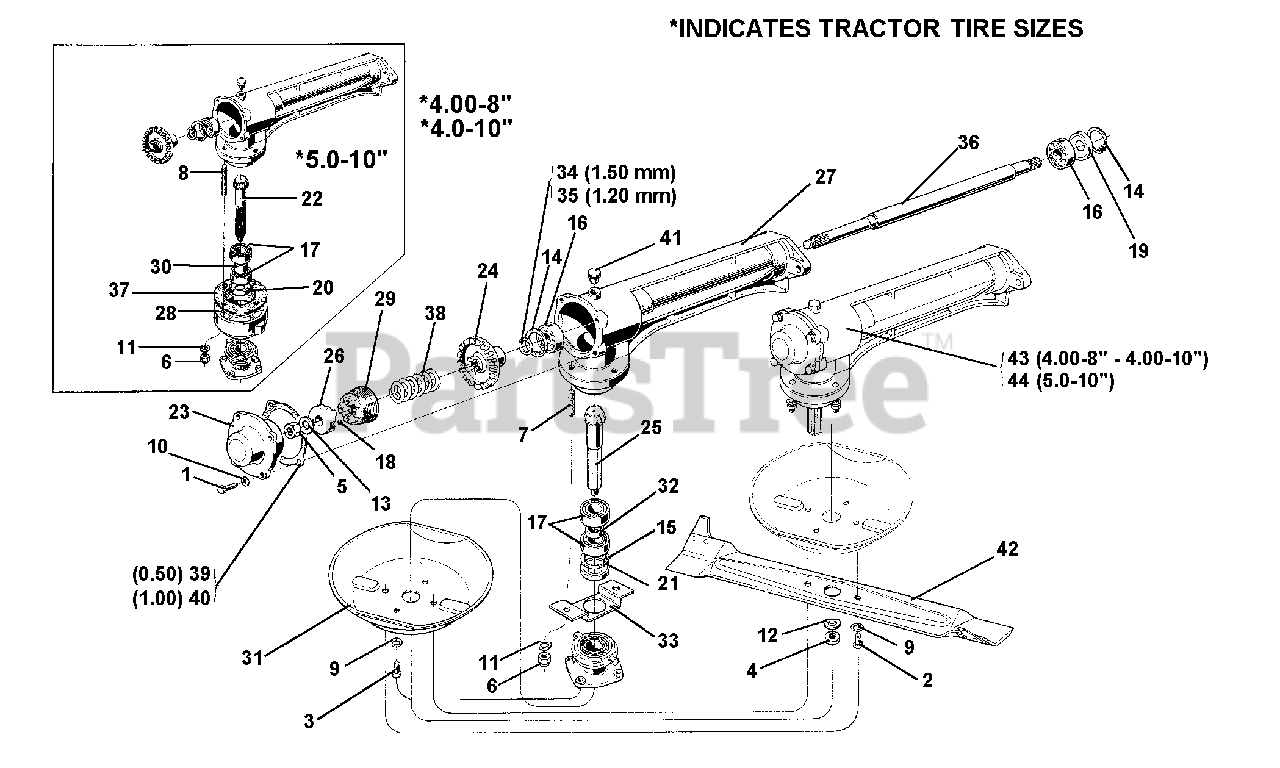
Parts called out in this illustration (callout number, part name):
1	SCREW M6 X 20
2	SCREW M8 X 14
3	SCREW M8 X 12
4	NUT, LOW M12
5	NUT M14 X 1.5
6	NUT, SELF LOCKING M10 LOW
7	STUD M10 X 37 X 19 X 15 8G
8	STUD M10 X 68 X 34 X 15
9	SUPER WASHER 8 DIN 6796
10	WASHER, LOCK 6.4
11	WASHER, LOCK 10.5
12	WASHER, LOCK 13
13	WASHER, LOCK 15
14	CIRCLIP, INTERN. D 47
15	CIRCLIP, INTERN. D 52
16	BEARING 20 X 47 X 14 6204
17	BEARING 25 X 52 X 15 6205
18	BALL 5/16 RIV RB 7.938
19	OIL SEAL 20 X 47 X 7
20	OIL SEAL 25 X 40 X 7
21	OIL SEAL 25 X 52 X 7
22	BEVEL PINION
24	CONICAL GEAR
26	BRAKE COUPLING
27	LAWN MOWER CASING 715
28	SPACER FLANGE
30	LONG SPACER
31	PROTECTION DISC
36	PROPELLER SHAFT
38	BRAKE SPRING
41	BREATHER CAP 1/4 GAS
42	LAWN MOWER BLADE
43	GEAR ASSEMBLY
44	GEAR ASSEMBLY
